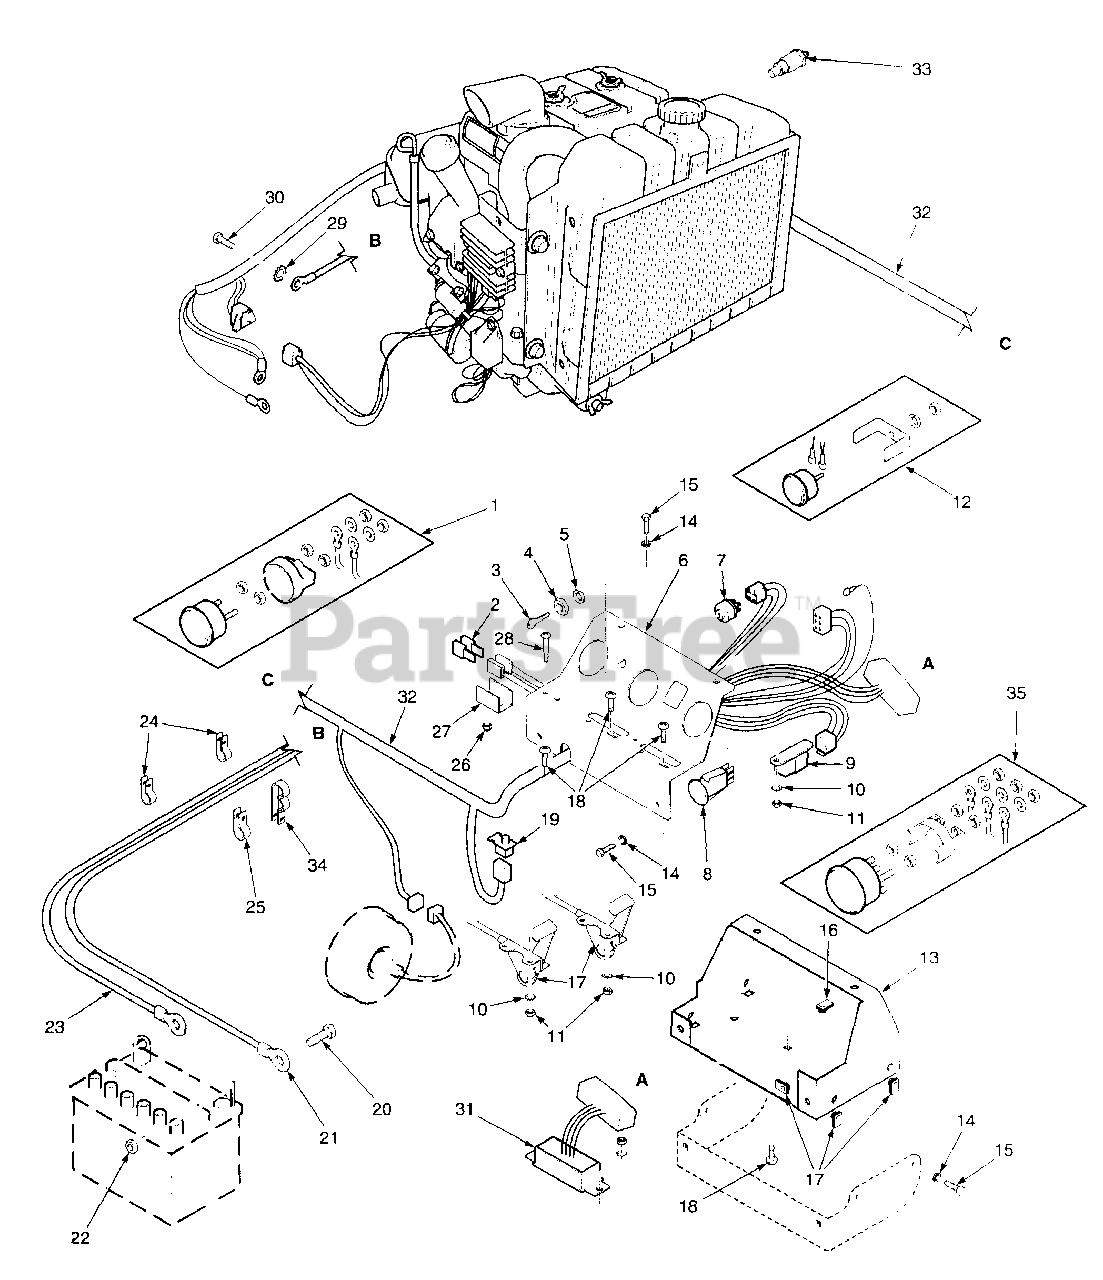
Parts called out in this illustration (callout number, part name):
1	Hour Meter
2	Fuse, 20 AMP
3	Key & Ring Assembly
4	Nut, Hex 5/8-32
5	Lockwasher, 5/8" Internal
6	Instrument Panel, Top
7	Key Switch
8	Switch, PTO
9	Relay
10	Lockwasher, #10 External Tooth
11	Nut, Hex #10-32
12	Ammeter
13	Base, Instrument Panel
14	Lockwasher, 1/4"
15	Bolt, Hex Head 1/4-20 x 3/4"
16	U-Nut, 1/4-20
17	Throttle And Choke Controls
18	Screw, Phillips Washer Head #10-32 x 1/2"
19	Switch, Interlock-Seat
20	Bolt, Hex Head 1/4-20 x 1/2"
21	Cable, Battery - Red 36"
22	Nut, Hex 1/4-20
23	Cable, Battery - Black
24	Clamp, Cable 1/2" ID.
25	Clamp, Cable 3/4" ID.
26	Nut, Hex Elastic Stop #10-32
27	Bracket, Fuse Holder
28	Screw, Phillips Washer Head #10-32 x 1-1/2"
29	Lockwasher, 5/16" External Tooth
30	Bolt, Hex Head M8-1.25 x 20
31	Electronic Module
32	Wire Harness, STT-KA
33	Sending Unit, Water Temp.
34	Clamp, Cable
35	Water Temp. Gauge
